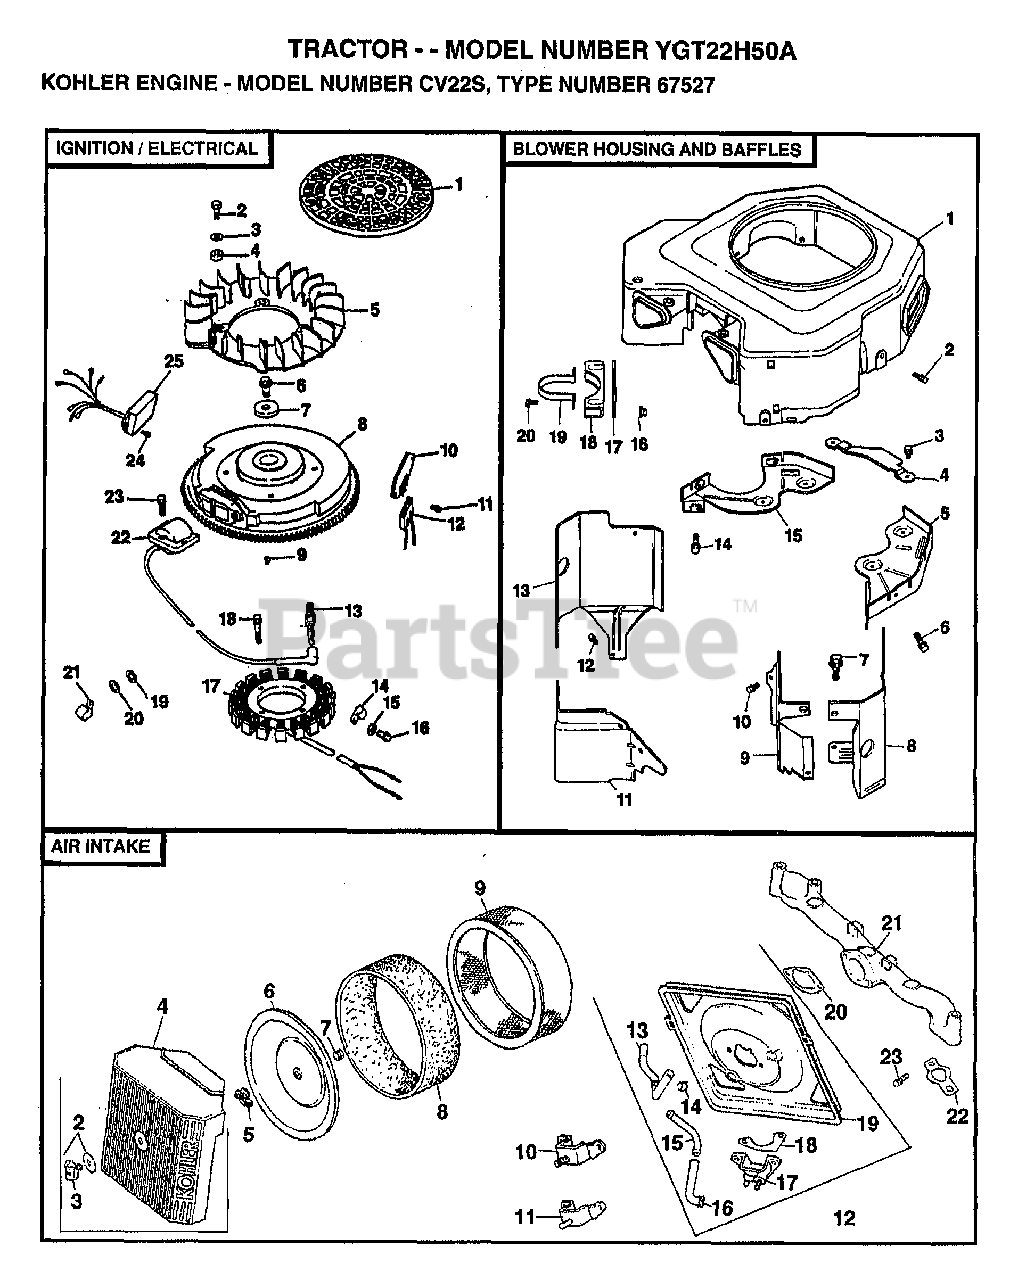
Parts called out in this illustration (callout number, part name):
1	SCREEN, GRASS
1	HOUSING
1	KIT, AIR CLEANER COVER
2	SCREW
2	KIT, KNOB W/GASKET
3	WASHER
3	SCREW
3	KNOB
4	SPACER
4	COVER, AIR CLEANER
5	FAN
5	GUARD
5	WING NUT
6	SCREW
6	COVER
7	SCREW
7	SEAL
8	FLYWHEEL ASSEMBLY
8	ELEMENT
9	KEY
9	BAFFLE
9	ELEMENT, AIR CLEANER
10	RECTIFIER-REGULATOR
10	SCREW, MOUNTING
10	BRACKET
11	SCREW
11	BAFFLE
11	BRACKET
12	CONNECTOR
12	SCREW
12	KIT, AIR CLEANER BASE
13	SPARK PLUG
13	BAFFLE
13	HOSE, BREATHER
14	CLIP
14	SCREW
14	CLAMP, HOSE
15	WASHER
15	PLATE
15	FITTING
16	SCREW
16	NUT
16	HOSE, BREATHER
17	STATOR
17	SPACER
17	CUP
18	SCREW
18	BRACKET, BREATHER SEPARATOR
18	GASKET
19	WASHER, PLAIN 1/4
19	STRAP, BREATHER SEPARATOR
19	BASE AIR CLEANER
20	WASHER
20	SCREW
20	GASKET
21	CLIP, CABLE
21	MANIFOLD
22	MODULE IGNITION
22	GASKET
23	SCREW, HEX SOCKET HD M5 X .8 X 25
23	SCREW HEX FLANGE M6 X 1.0 X 55
24	SCREW HEX FLANG M4 X .7 X 10
25	MODULE, SPEED ADVANCE
